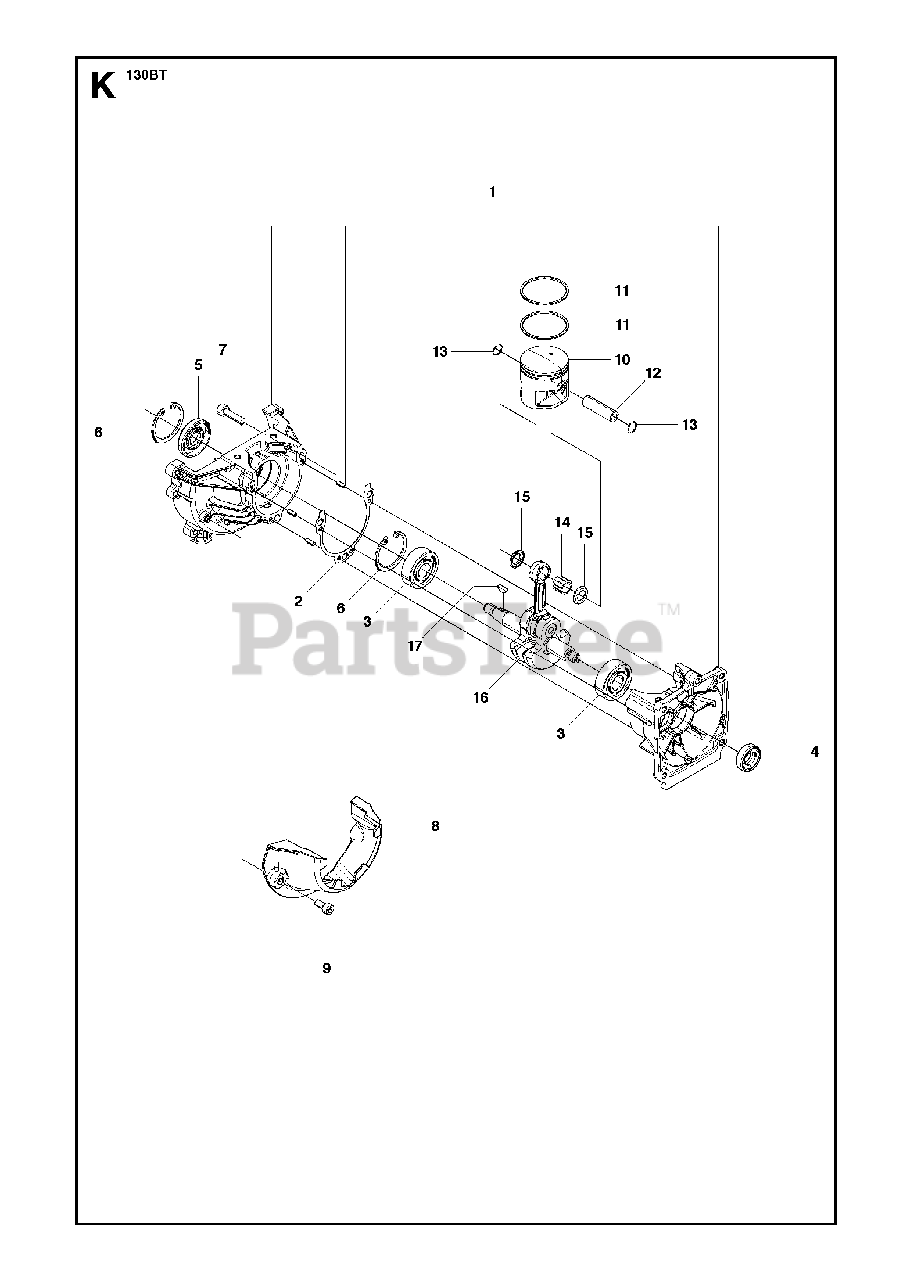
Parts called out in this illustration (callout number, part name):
1	CRANKCASE-C
2	GASKET CASE
5	SEAL
7	BOLT
9	BOLT 08
12	PISTON PIN
16	CRANKSHAFT C
